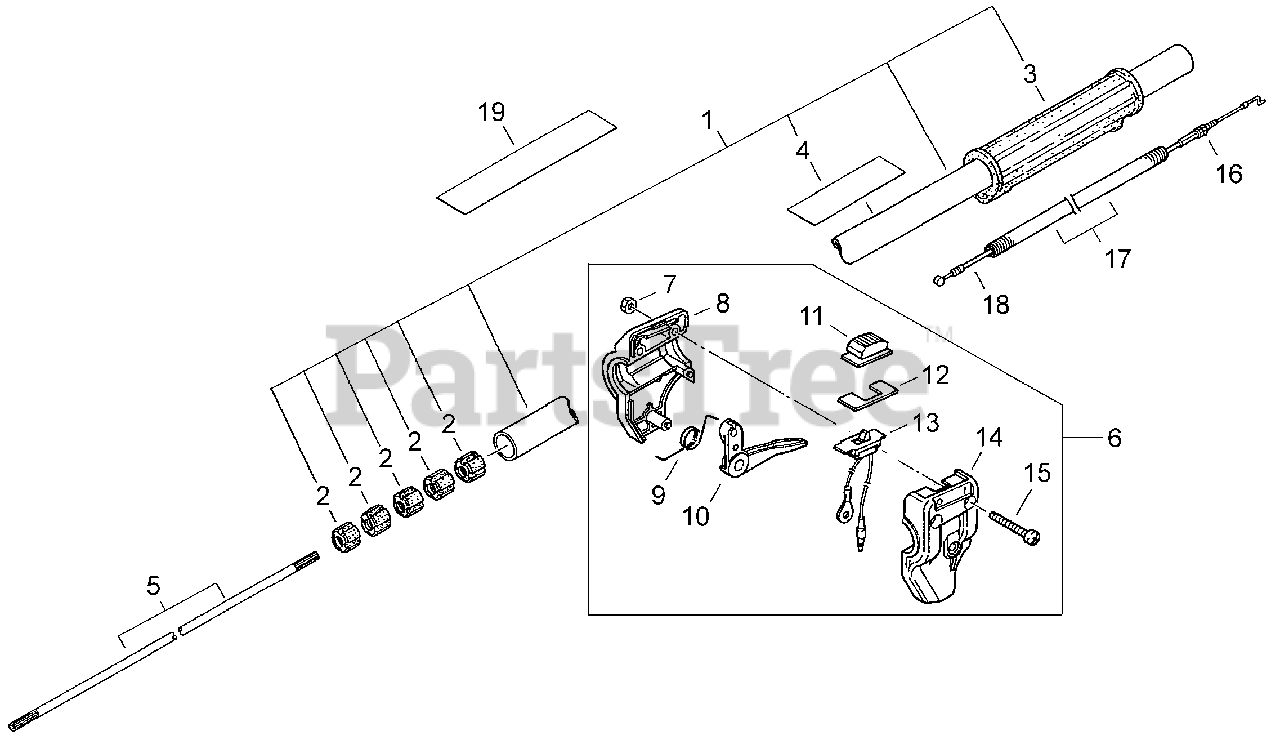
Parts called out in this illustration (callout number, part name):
2	BUSHING
3	GRIP
4	LABEL, CAUTION
5	MAINSHAFT
6	THROTTLE CONTROL ASSY
7	NUT M5
8	CONTROL HANDLE - RIGHT
9	SPRING, RETURN
9-1	MAIN PIPE ASSY
10	TRIGGER, THROTTLE
11	KNOB, SWITCH
12	PLATE, SWITCH
13	SWITCH, ON-OFF
14	CONTROL HANDLE - LEFT
15	SCREW M5×30
16	NUT M6
17	TUBE, FLEXIBLE
18	CABLE, THROTTLE
19	LABEL, SHINDAIWA
